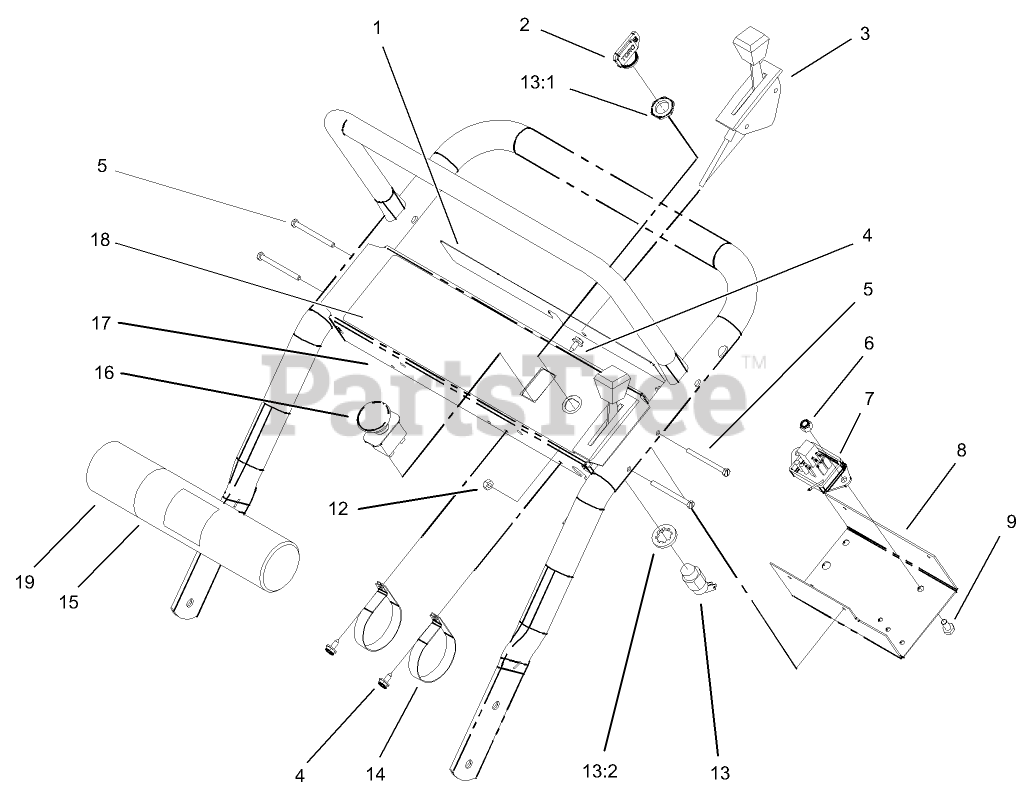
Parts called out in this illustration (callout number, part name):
1	DECAL-DANGER
2	KEY-IGNITION
3	CONTROL-THROTTLE
4	SCREW-HWHTF
5	SCREW-SHH
6	NUT-LOCK, NI
7	MODULE-DELAY
8	PANEL-BOTTOM
9	SCREW-HH
12	NUT-LOCK, NI
13	SWITCH-ON / OFF
13:1	NUT-HH
13:2	WASHER-TOOTH, INTERNAL
14	CLAMP-R
15	TUBE-MANUAL
16	SWITCH-PTO
17	PANEL-CONTROL
18	DECAL-CONTROL PANEL
19	CAP-HOUSING
